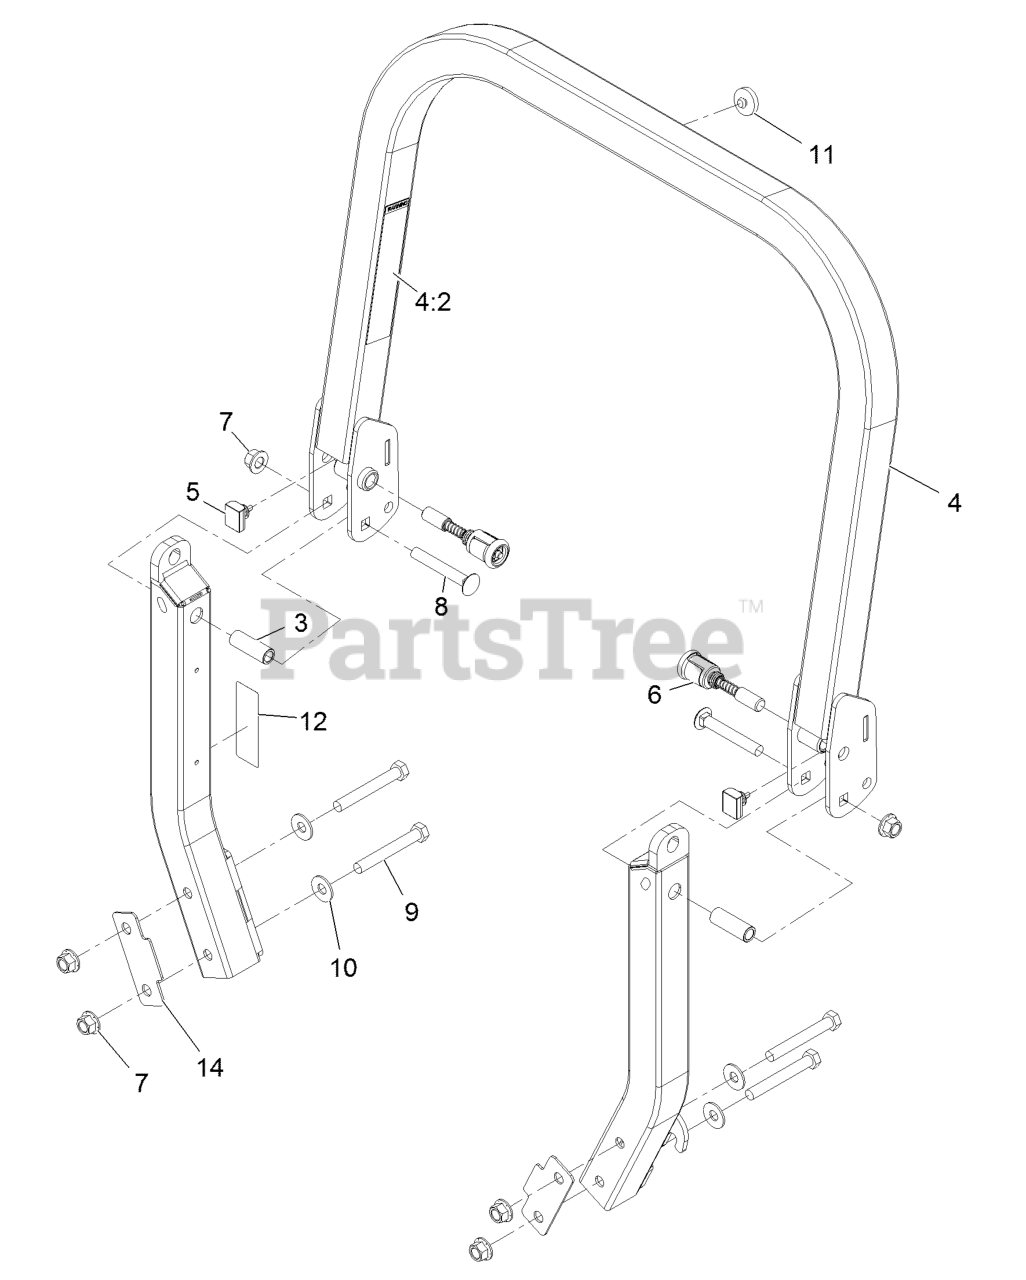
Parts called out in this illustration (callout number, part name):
4	UPPER ROPS ASM
4:2	DECAL-WARNING, FOLDING RO
5	BUMPER-ROPS
6	PIN-SPRING
7	Nut-Lock 1/2-13
8	SCREW-CARR
9	WASHER-LOCK
10	WASHER-SPRING
11	BUMPER-PUSH-IN, RUBBER
12	DECAL-CAUTION
